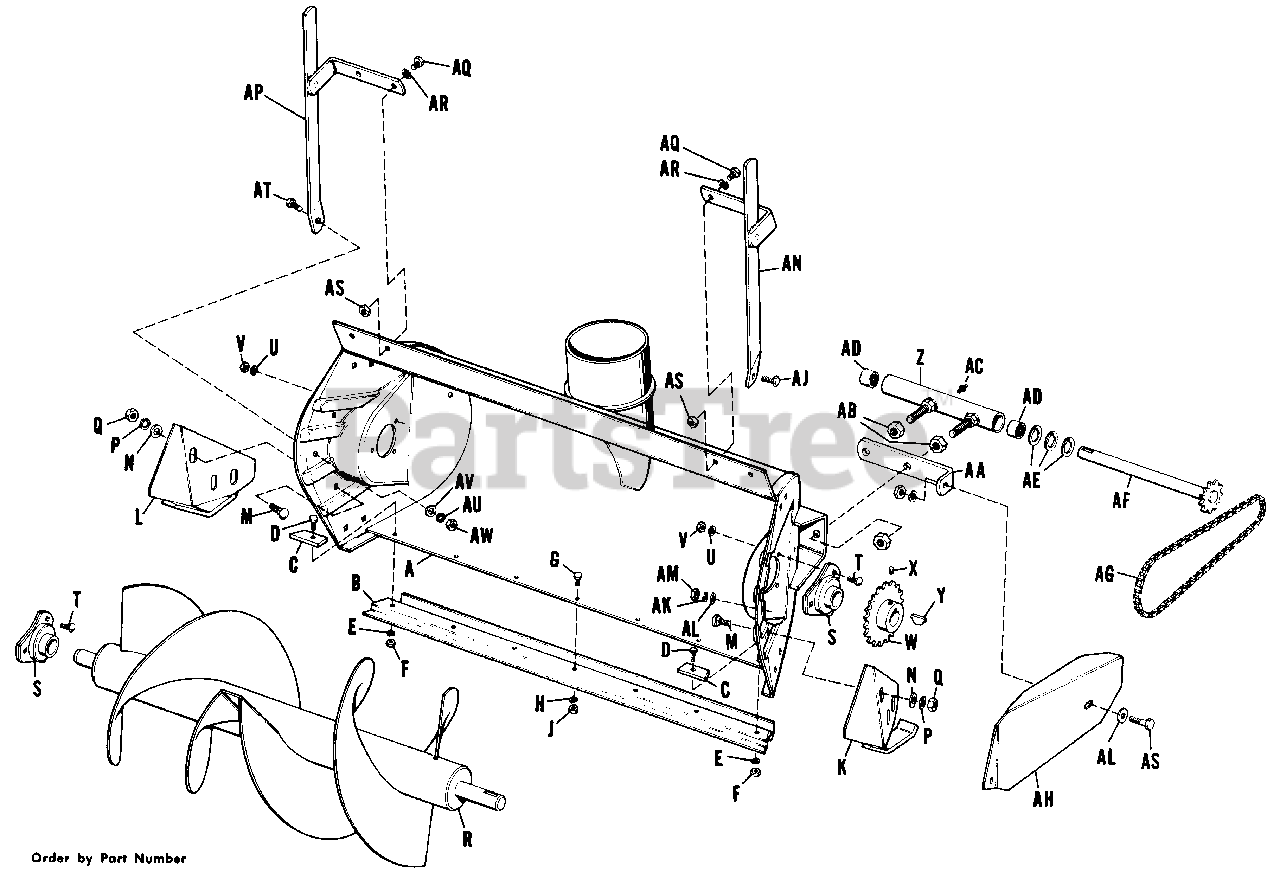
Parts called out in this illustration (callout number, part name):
A	Body Assembly
B	Scraper, Body
C	Clamp, Scraper
D	Capscrew, Hex Hd., 5/16"-18 N.C. x 3/4" lg.
E	Washer, Lock, 5/16"
F	Nut, Hex, Full, 5/16"-18 N.C.
G	Capscrew, Hex Hd. 1/4"-20 N.C. x 1/2" lg.
H	Washer, Lock, 1/4"
J	Nut, Hex, Full, 1/4"-20 N.C.
K	Shoe Assy., L.H.
L	Shoe Assy., R.H.
M	Bolt, Carriage, 3/8"-16 N.C. x 3/4" lg.
N	Washer, Plain, 3/8"
P	Washer, Lock, 3/8"
Q	Nut, Hex, Full, 3/8"-16 N.C.
R	Rotor Assembly
S	Bearing, Ball
T	Bolt, Carriage, 5/16"-18 N.C. x 3/4" lg.
U	Washer, Lock, 5/16"
V	Nut, Hex, Full, 5/16"-18 N.C.
W	Sprocket, Rotor
X	Set Screw, Cup Point, Hex Socket, 5/16"-18 N.C. x 5/16" lg.
Y	Key, "Hi-Pro"
Z	Housing Assy. Bearing
AA	Bracket, Chain Guard
AB	Nut, Hex, Full, 1/2"-13 N.C.
AC	Fitting, Grease
AD	Bearing, Needle
AF	Shaft Assy.
AG	Chain, Rotor
AH	Guard, Chain
AJ	Capscrew, Hex Hd., 5/16"-18 N.C. x 3/4" lg.
AK	Washer, Lock, 5/16"
AL	Washer, Plain, 5/16"
AM	Nut, Hex, Full, 5/16"-18 N.C.
AN	Cutter Assembly, Drift, L.H.
AP	Cutter Assembly, Drift, R.H.
AQ	Capscrew, Hex Hd. 5/16"-18 N.C. x 5/8" lg.
AR	Washer, Lock, 5/16"
AS	Nut, Hex, Full, 5/16"-18 N.C.
AT	Capscrew, Hex Hd., 5/16"-18 N.C. x 3/4" lg.
AU	Washer, Lock, 5/16"
AV	Washer, Plain, 5/16"
AW	Nut, Hex, Full, 5/16"-18 N.C.
